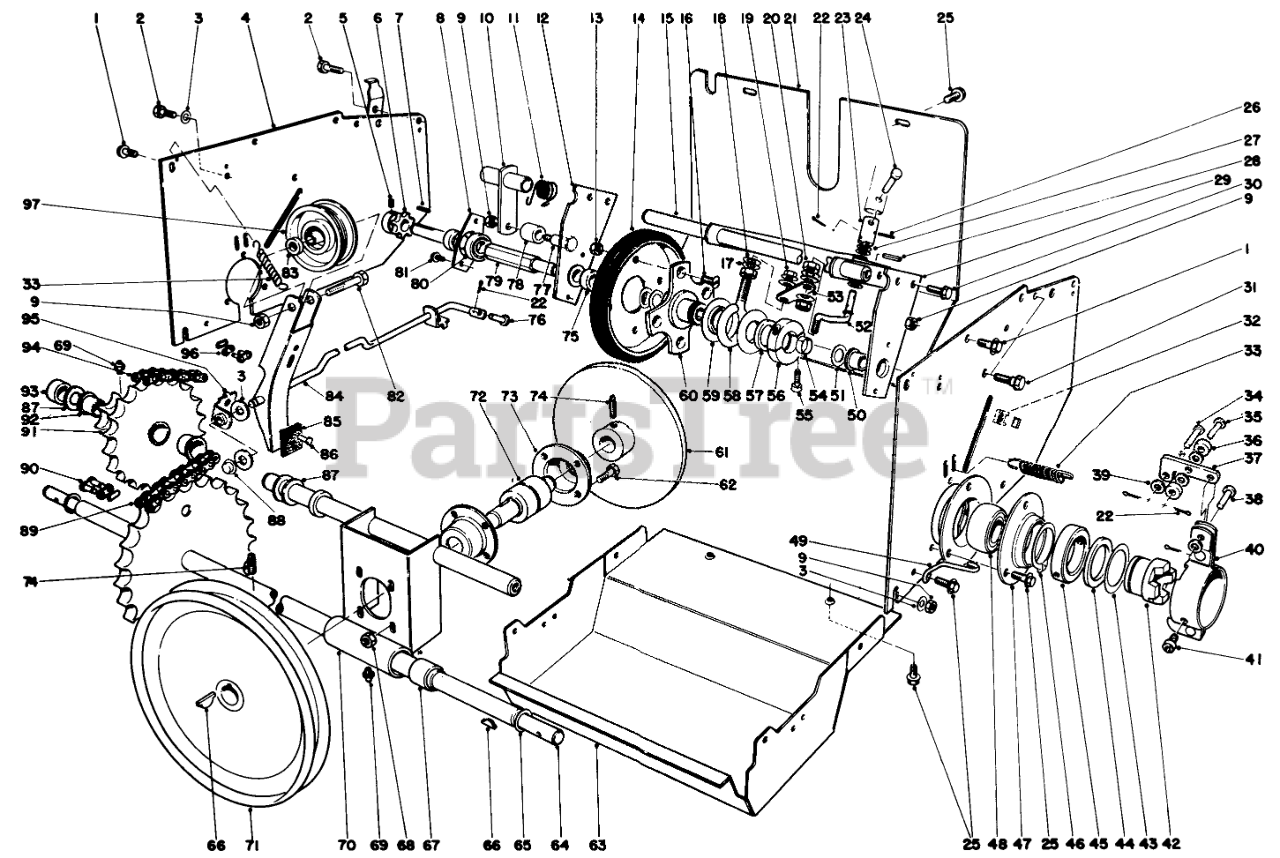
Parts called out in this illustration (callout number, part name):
1	SCREW-HH
2	SCREW-HHFTF
3	WASHER-FLAT
4	Side Plate Drive
5	SCREW-HSH
6	SPROCKET
8	BEARING CUP
9	NUT-HEX
10	CHAIN TENSION ARM WA
11	TORSION SPRING
12	HEX SHAFT MOUNT R
13	Nut
14	Disc
15	Bracket Dead Shaft
16	5/16-18X5/8 FLT HD MS
17	WASHER-FLAT
18	WASHER-SPRING
19	NUT-LOCK, FLANGE
20	Nut
21	REAR COVER R
22	PIN-COTTER
23	U JOINT TUBE
24	CLEVIS PIN
25	SCREW-HWH
26	PIN-SPRING
27	Clevis Pin
28	PIN-ROLL
29	Hex Shaft Mounting (Incl. Ref. #50)
30	SCREW-HWHTF
31	SHOULDER SCREW
32	Retained Nut
33	EXTENSION SPRING
34	PIN-CLEVIS
35	PIN-CLEVIS
36	CLUTCH ROLLER
37	CLUTCH CAM ARM
38	PIN-CLEVIS
39	WASHER-FLAT
40	CLUTCH MT BRKT ASM
41	SCREW-HSH
42	WHEEL CLUTCH
43	THRUST WASHER
44	THRUST BEARING
45	CLUTCH MOUNT COLLAR
46	RING-RETAINING, EXTERNAL
47	BEARING FLANGE
48	BEARING
49	Clutch Retainer
50	BUSHING
51	WASHER-FLAT
52	CONNECTION ROD
53	SHIFT ROD PIVOT
54	SPLIT SPACER
55	SCREW-HSH
56	ColIar
57	WASHER-THRUST
58	SLIDER RING COLLAR
59	SLIDER RING
60	TRACTION DISC HUB
61	FRICTION PLATE O
62	SCREW-HH
63	LOWER SHIELD R
64	AXLE SHAFT WA
65	WASHER
66	KEY-WOODRUFF
67	BUSHING
68	NUT-KEPS
69	FITTING-GREASE
70	Bulkhead (Incl. Ref. #67)
71	Pulley
72	BEARING-FRICTION PLATE
73	HOUSING BEARING
74	SCREW-SET, SQH
75	SPACER
76	PIN-CLEVIS
77	SHOULDER BOLT
78	CHAIN TENSION ROLLER
79	FRICTION WHEEL SHAFT
80	BEARING
81	SCREW
82	SCREW-HH
83	Spacer
84	Auger Brake Assembly (Incl. Ref. #85-86)
85	BRAKE PAD
86	.185 DIA X .375 RT +
87	WASHER-THRUST
88	PUSH NUT
89	ROLLER CHAIN
90	LINK-CHAIN
91	Sprocket (Incl. Ref. #69 & 92)
92	3/4ID X 3/4LG BSHG
93	SPACER-IDLER
94	1/4 X 42 CHAIN W/LINK
95	Bracket-Clutch
96	LINK-CONNECTING
97	PULLEY-IDLER
